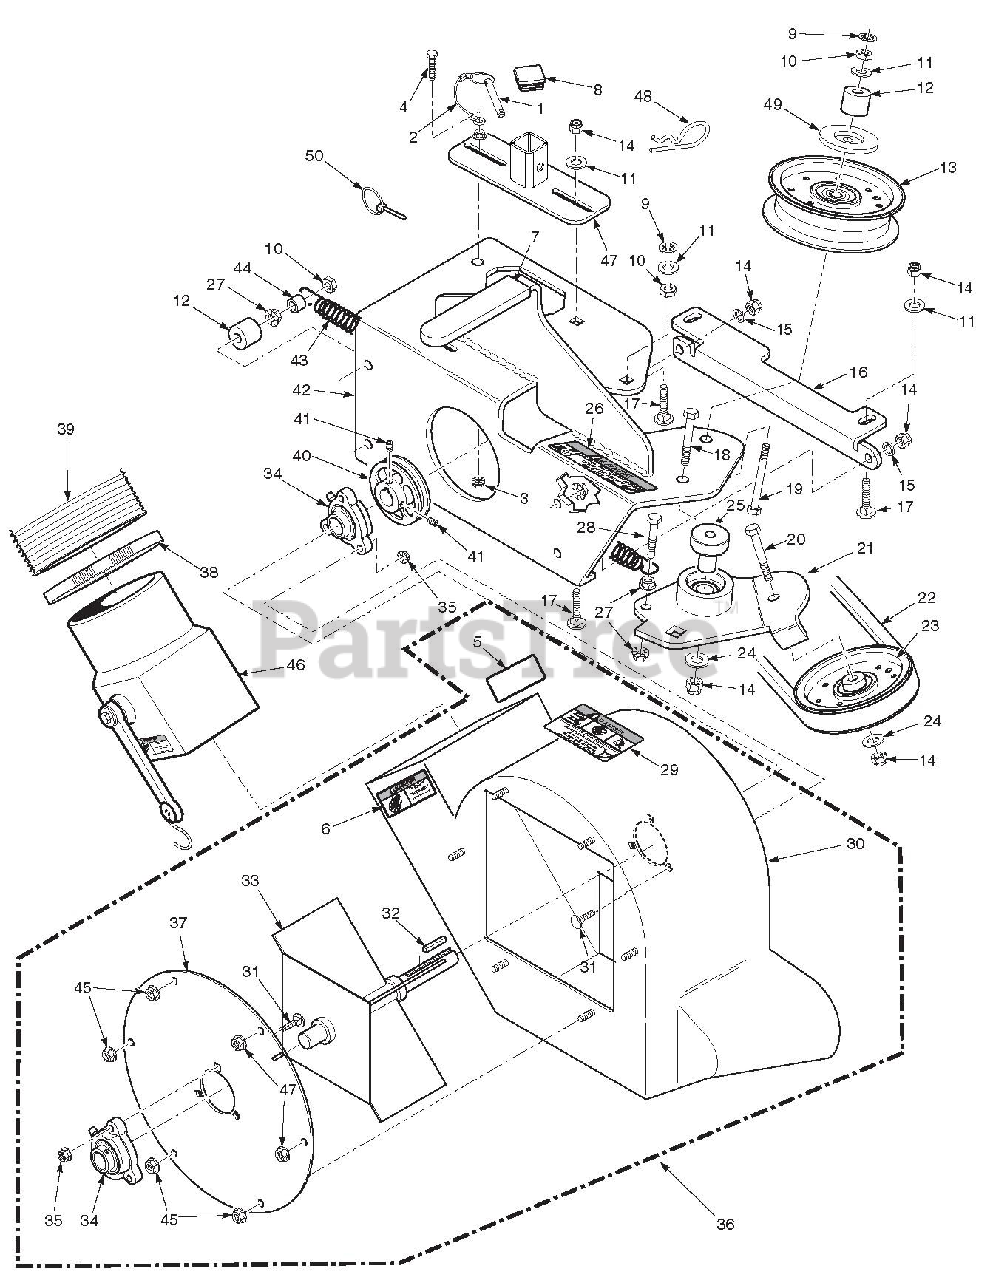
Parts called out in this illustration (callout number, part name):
1	Pin, Ring 2-1/4" Long
2	Lanyard, Deck Height Pin
3	Nut, Serr. Flange 1/4-20
4	Bolt, Hex Head 1/4-20 x 1-1/4"
5	Decal, Blower
6	Decal, Rotating Blower
7	Grip, Blower Lever
8	Cap, Square
9	Nut, Push On 3/8 Thread
10	Lock Nut, 3/8-16
11	Flatwasher, 3/8-.391 x .938 x .105
12	Spacer
13	Pulley, Idler 3-1/2" Dia.
14	Nut, Elastic Stop 3/8-16
15	Lockwasher, 3/8-16
16	Plate, Catcher Mounting
17	Bolt, Carr. 3/8-16 x 1-1/2"
18	Bolt, Hex Head 3/8-16 x 3" - 52"
19	Bolt, Hex Head 3/8-16 x 3-1/2"
20	Bolt, Hex Head 3/8-16 x 1-3/4"
21	Idler Arm Assembly
22	Belt, GC-STT-52V / STTII-52V
23	Pulley, 3-1/2" O.D., GC-STC
24	Washer, 3/8 Hardened
25	Pivot, Idler
26	Decal, Belt Cover
27	Nut, Serr. Flange 3/8-16
28	Bolt, Hex Head 3/8-16 x 1-1/2 Gr. 8
29	Decal, Danger
30	Blower Housing Weldment
31	Bolt, Carr. 5/16-18 x 3/4" Gr. 5
32	Key, 1/4 x 1/4 x 1-1/2"
33	Fan Weldment
34	Bearing Assembly
35	Nut, Elastic Stop 5/16-18
36	Blower Housing Assembly
37	Cover, Blower Housing
38	Clamp, 8-5/8" Max Dia.
39	Hose, 8.00" Dia. x 68" Long
40	Pulley, 4-3/4" O.D. - 1" Bore
41	Set Screw, 5/16-18 x 3/8"
42	Frame, Blower Mount
43	Spring, Main Drive
44	Spacer
45	Nut, Serr. Flange 5/16-18
46	Adapter w/Strap
47	Receiver Weldment, Mounting Post
48	Hair Pin Cotter, .177 x 3-1/4"
49	Dust Shield
50	Quick Pin, 5/16" Dia.
